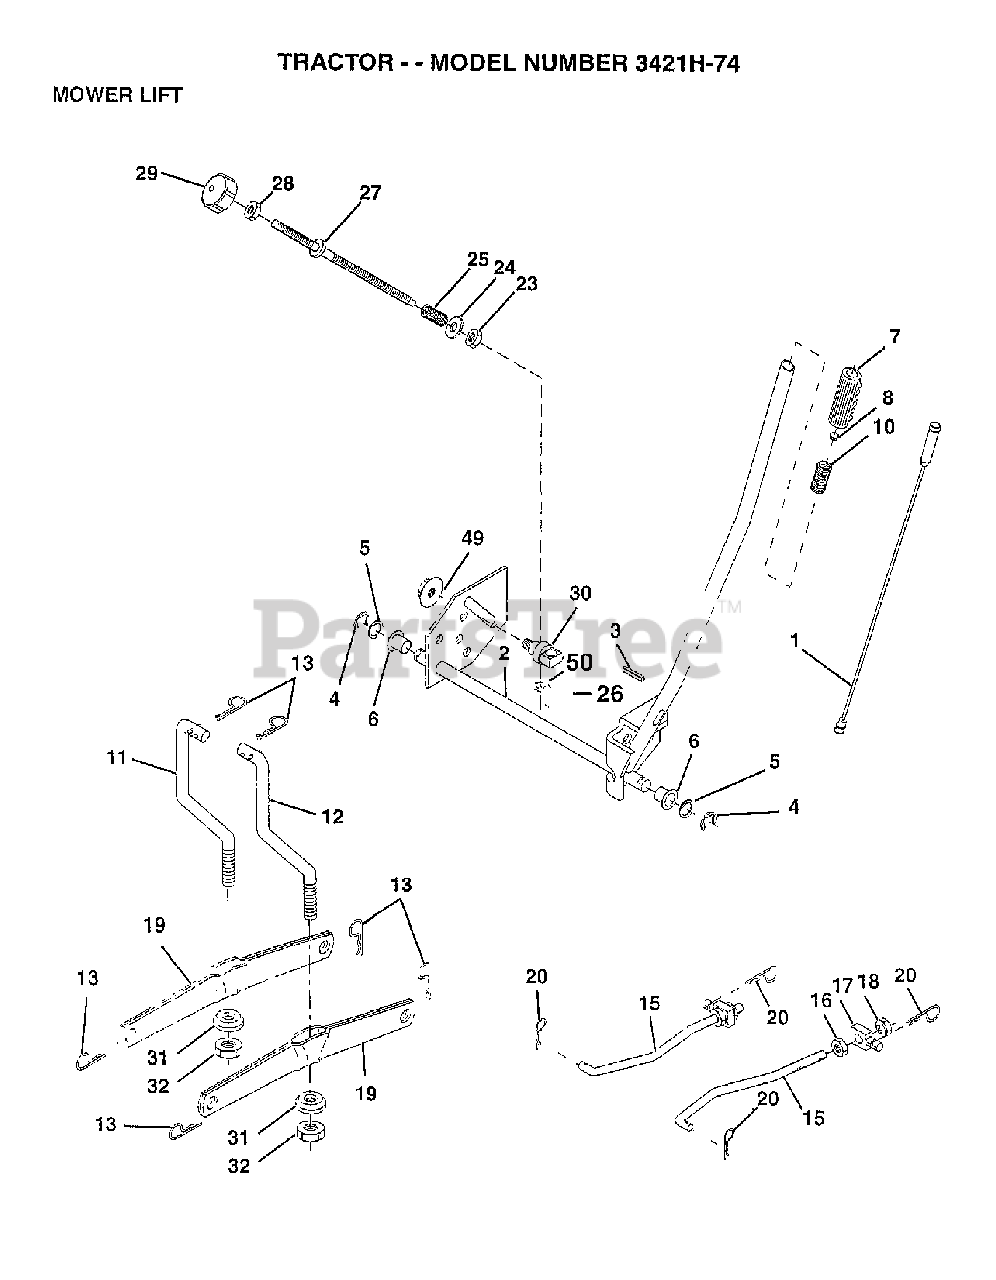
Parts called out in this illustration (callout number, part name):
3	PIN GROOVE
4	RETAINING RING LT
6	BEARING.NYLON
7	GRIP
8	PLUNGER BUT KIT
10	SPRING, COMP T
11	LINK LIFT LH
12	Lift Link Assembly, RH
13	RETAINER SPRING
15	FRONT LINK
16	NUT.HEX.JAM.1/2-13
18	NUT.LK.W/WSH.1/2.
19	ARM.REAR.SUSPENSION
20	SPRING RETAINER
24	WASHER
25	SPRING.COMP.INF.H
27	ROD.LIFT.ADJUSTABLE
28	NUT
29	KNOB INF 3/8-16
30	TRUNNION
32	NUT CROWNLOCK 3/8-24
49	Flange Hex Lock Nut, 3/8-16
50	NUT PUSH M
